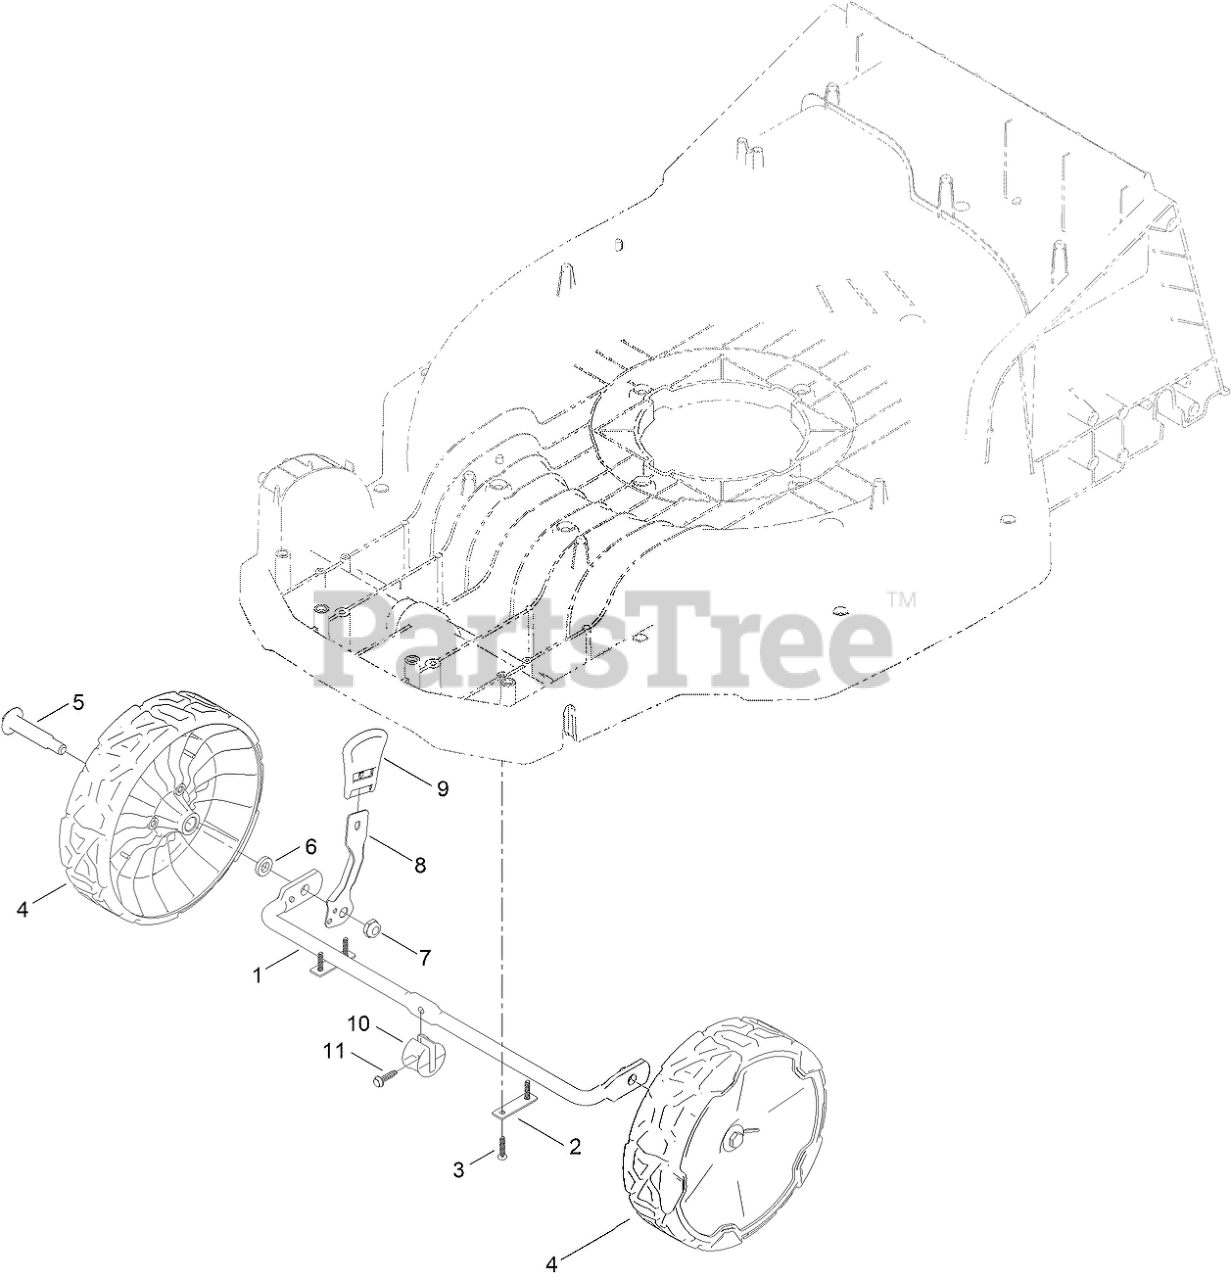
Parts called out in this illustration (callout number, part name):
1	AXLE-FRONT
2	STRAP-AXLE
3	SCREW-PPH
4	ASM-8" WHEEL, IDLER
5	BOLT-SHOULDER
6	WASHER-WHEEL BOLT
7	NUT-HEX
8	ARM-SPRING
9	KNOB-HOC
10	STOP-AXLE
11	SCREW-HWH
